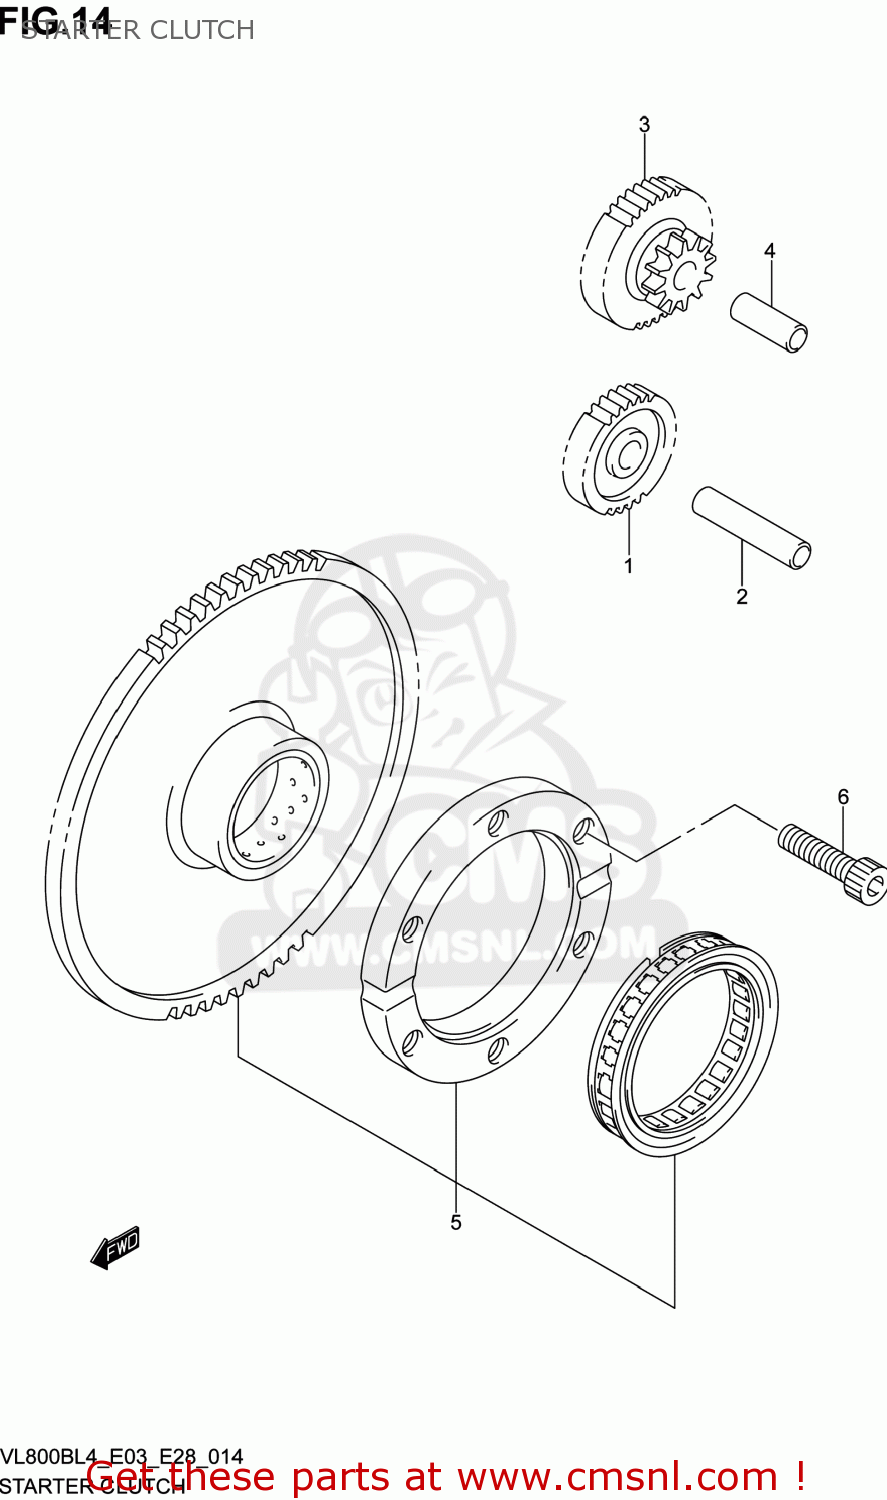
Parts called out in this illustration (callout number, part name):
1	GEAR,STARTER IDLE NO.1
2	PIN,10X43
3	GEAR,STARTER IDLE NO.2
4	PIN
5	CLUTCH SET,STARTER
6	BOLT(8X30)
